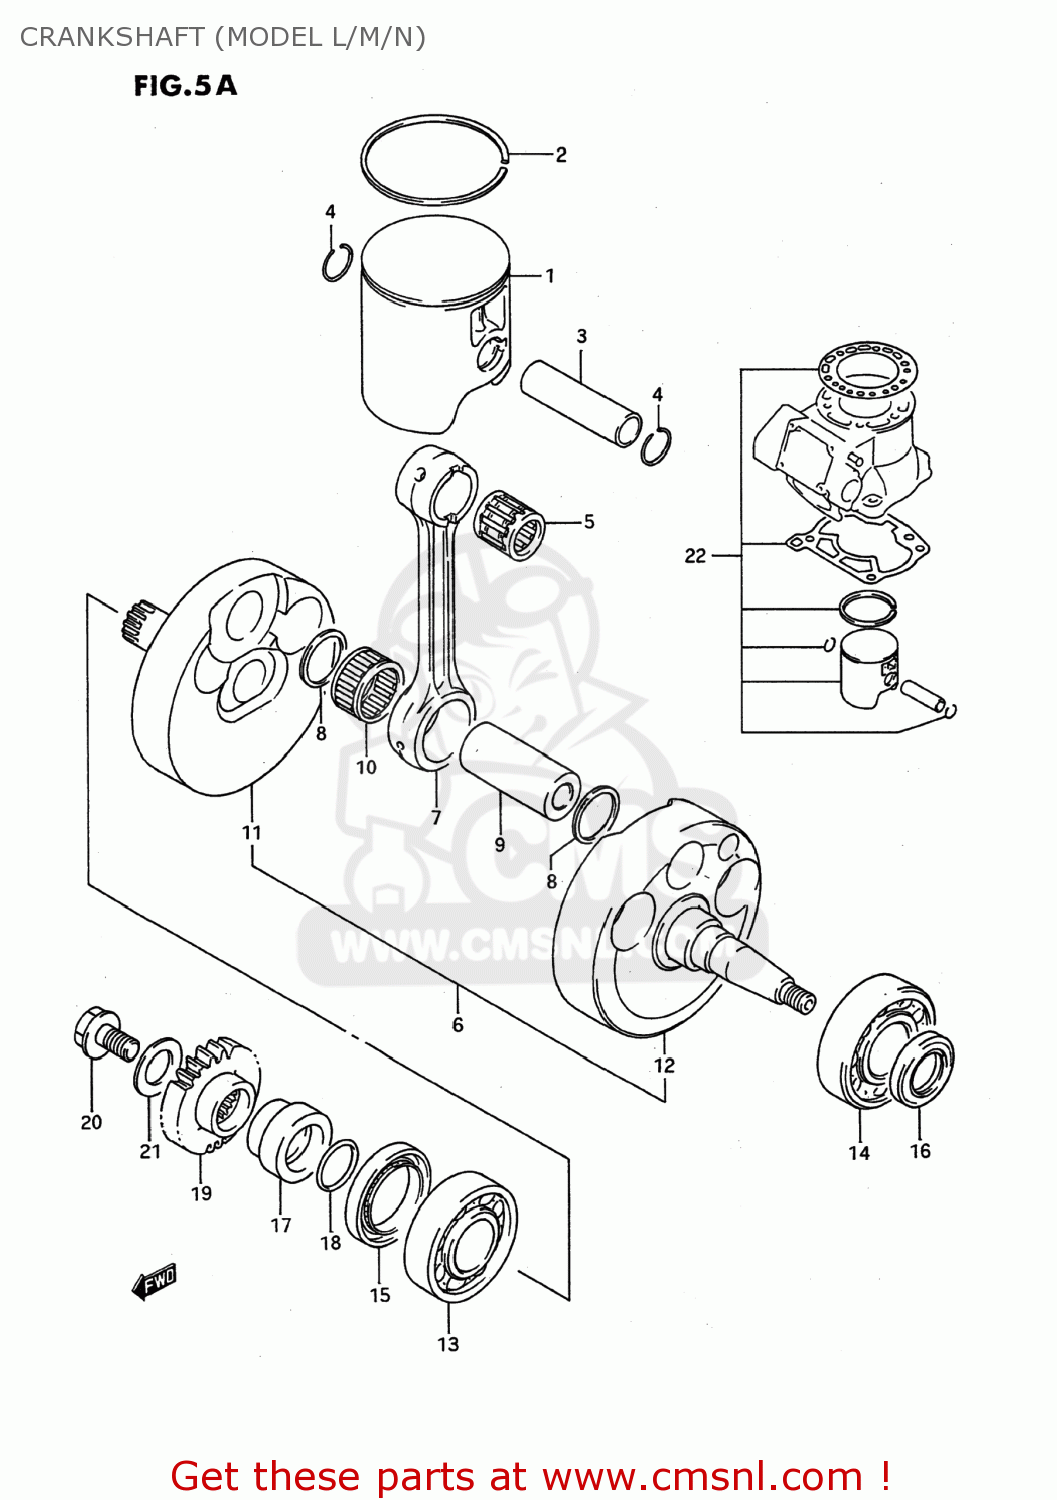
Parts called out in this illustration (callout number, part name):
1	PISTON (67.00MM)
2	RING,PISTON
3	PIN,PISTON
4	CIRCLIP
5	BEARING(18X23X22)
6	CRANKSHAFT ASSEMBLY
7	ROD,CONNECTING
8	WASHER(24X29X1.5)
9	PIN,CRANK
10	BEARING
11	CRANKSHAFT,RIGHT
12	CRANKSHAFT,LEFT
13	BEARING(25X62X17)
14	BEARING(28X68X18)
15	OIL SEAL
16	SEAL,OIL(25X37X6)
17	SPACER,PRIMARY DRIVE GEAR
18	O RING(D:2.4,ID:21.8)
19	GEAR,PRIMARY DRIVE
20	BOLT,PRIMARY DRIVE GEAR
21	WASHER
22	TOP END KIT,ENGINE
